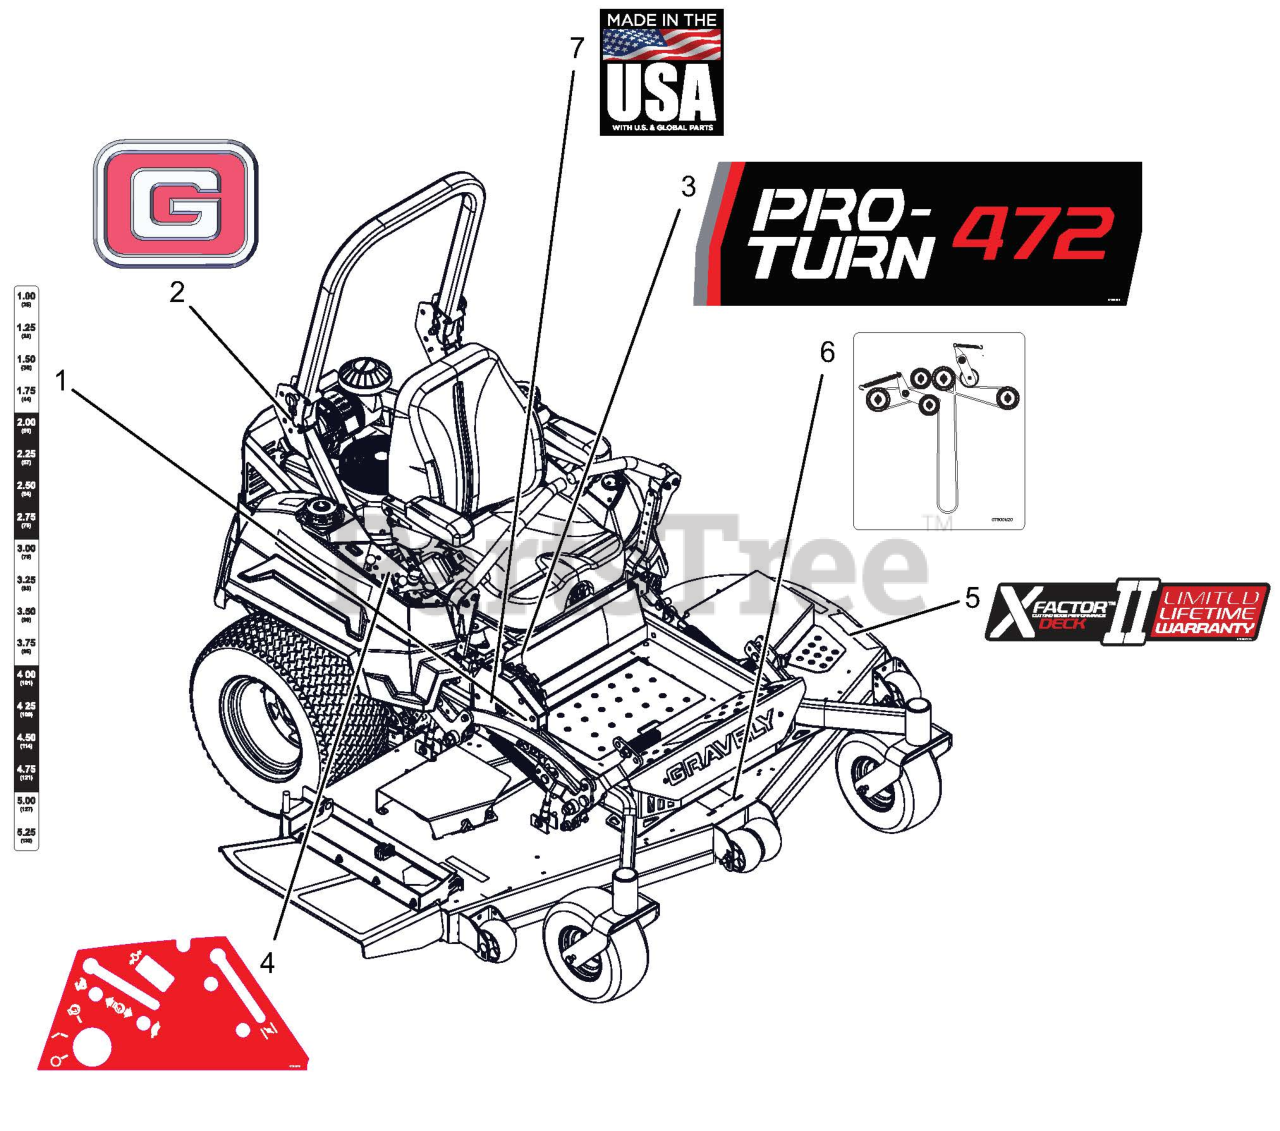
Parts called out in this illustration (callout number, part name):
1	DECAL, PT400 HEIGHT OF CUT
2	DECAL, GRAVELY BRAND
3	DECAL, PRO-TURN 472
4	DECAL, NON-EFI CONTROL PANEL
5	DECAL, X-FACTOR DECK
6	DCL,BELT ROUTE-RH BK-SIDE IDLR
7	DECAL, MADE IN USA
